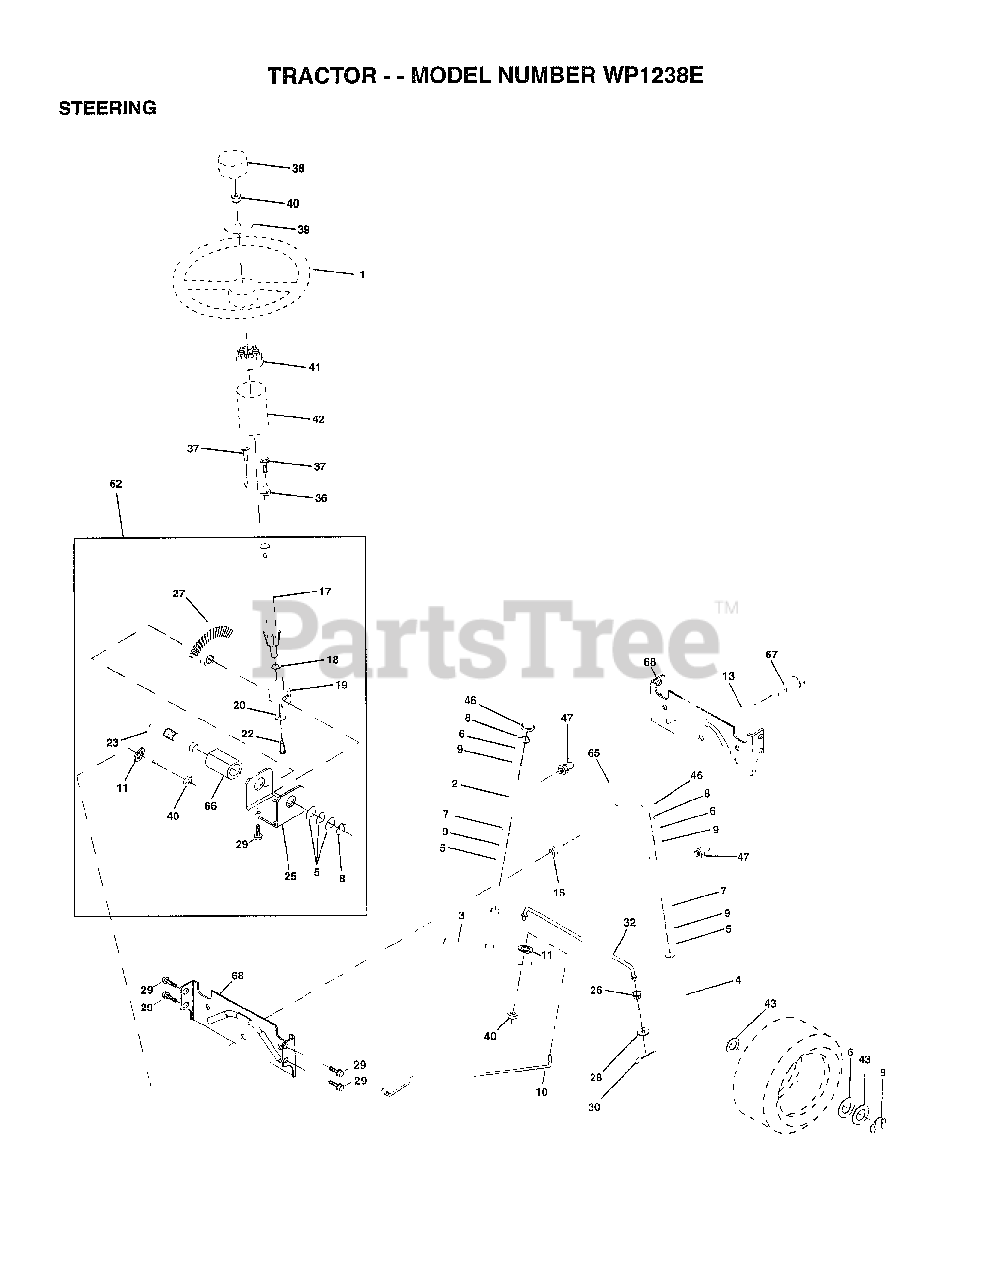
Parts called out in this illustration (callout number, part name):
2	AXLE ASM
3	SPINDLE.ASM.LH
4	"SPINDLE ASM,RH"
5	WASHER .T
6	WASHER
7	WASHER
8	RING
9	COL. SRTG. BEAR.
10	DRAGLINK-STAMPED
11	LOCKWASHER
13	BEARING AXLE
15	"NUT-LOC,FLANGE LT"
17	SHAFT ASSM STEERN
18	THRUST WASHER
19	SUPPORT.SHAFT
22	SCREW HEX SOC1/4-
25	BRKT-STEERING
26	BUSHING.DRAGLINK
27	GEAR SECTOR
28	WASHER
29	SCREW
30	COTTER PIN
32	TIE ROD
36	BUSHING.STEERING
37	"SCREW-TT,10-32 FL"
38	ST WHL INSERT CAP
39	WASHER T
40	GRIPCO NUT
41	ADAPTER-WHEEL LT
42	"TUBE, STR SHAFT"
46	CAP
47	ZERK M
62	STEERING ASM KIT
65	SPACER AXLE
66	"BEARING-ARM,PITMA"
67	BOLT
68	BRACE AXLE
